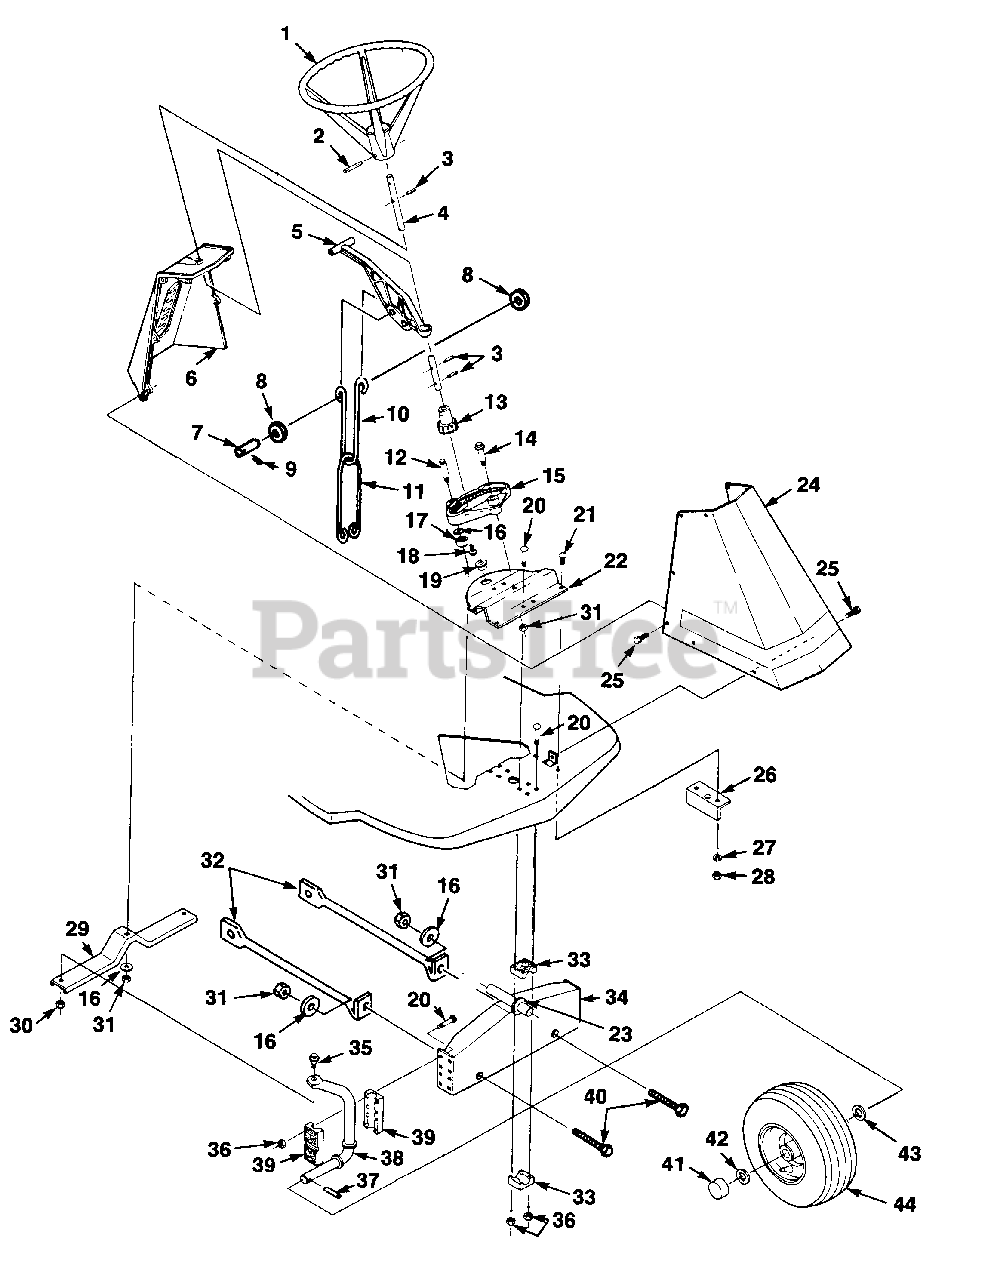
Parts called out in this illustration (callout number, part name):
7	PIN- Retainer
9	PIN- Cotter 1/8 x 3/4
10	LINK- Front Lift
11	LINK- Lower front lift
13	PINION- Steering
16	Superseded by PS84010
20	BOLT- 1/4-20 x 1 3/4 Carr.
23	WASHER- Flat (3/4")
24	SUPPORT- Steering
28	Superseded by JA993730
31	Nut (Hex Locking)
32	SUPPORT- Front axle
35	BOLT- 5/16-18
36	Nut - hex 1/4-20 lock
37	Superseded by 70763
40	SCREW- 3/8-16 x 5/8
